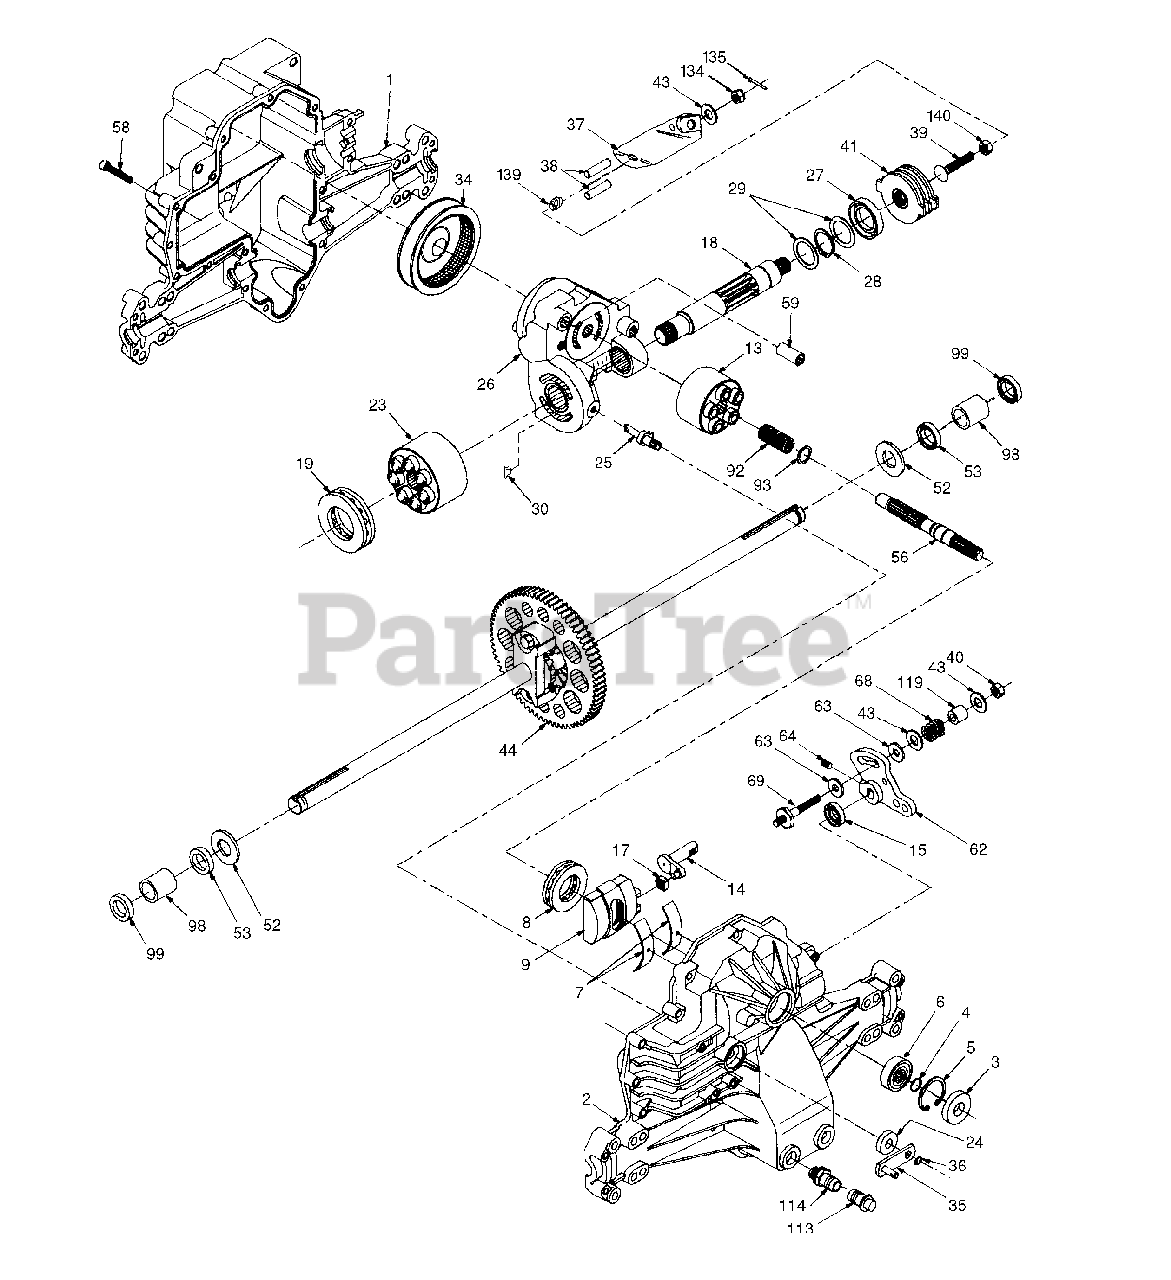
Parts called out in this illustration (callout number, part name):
1	Housing, Lower
2	Assembly, Upper Housing
4	Ring, Wire Retaining
5	Ring, Retaining
6	Bearing, Shaft Ball
7	Bearing, Cradle
8	Bearing, Thrust 30 x 52 x 13
9	Swashplate, Variable
13	Block, Cylinder Assembly
14	Arm, Trunnion
17	Guide, Slot
18	Shaft, Motor
19	Bearing, Thrust 42 x 68 x 16
23	Block, Cylinder Assembly
24	Seal, Lip 10 x 25 x 7
25	Actuator, Bypass
26	Center Section Assembly Kit
27	Seal, Lip 26 x 42 x 8
28	Ring, Retaining
29	Washer 26 x 35 x 1
34	Oil Filter Element
35	Arm, Bypass
36	Ring, Retaining
37	Arm, Actuating
38	Pin, Actuating
39	Bolt 5/16-24 x 1-3/4
40	Locknut, Hex 5/16-24 UNJC
41	Brake Rotor/Stator Kit
43	Washer 7/16 x 7/8 x .060
44	Differential Assembly
52	Washer 3/4 x 1.5 x .13
53	Seal .75 x 1.25 x .250
56	Shaft, Input
58	Bolt 1/4-20 x 1.38
59	Pin .5 OD x .43 ID x .750
62	Arm, Control
63	Puck, Dampener
69	Stud 5/16-24
92	Spring, Block
93	Washer, Block Thrust
98	Sleeve Bearing
99	Seal, Wiper
113	Cap, Vent Assembly
114	Fitting, O-Ring Assembly
119	Spacer
134	Nut, Castle 5/16-24
135	Pin, Cotter
139	Spring, Compression
140	Nut, Hex 5/16-24
